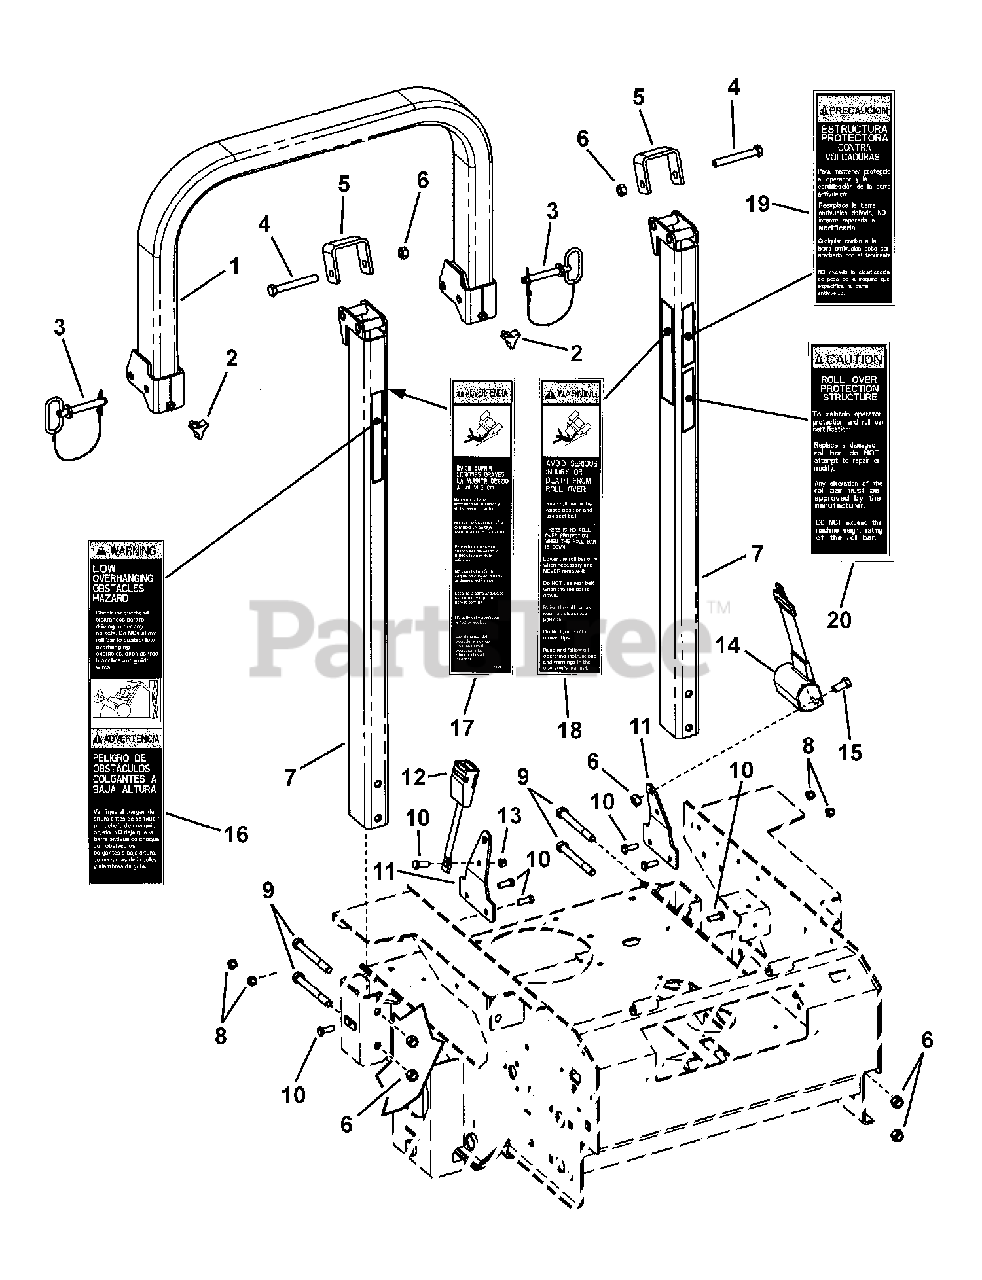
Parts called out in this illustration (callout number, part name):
1	WELDMENT, Loop
2	STAR KNOB (5/16-18 thread)
3	PIN, Hinge (ROPS)
4	BOLT, 1/2-13 x 3-3/4" Hex Head Cap
5	BRACKET, ROPS Stop, NZMX
6	NUT, 1/2-13 Hex Center Lock, GR 5
7	WELDMENT, Post
8	NUT, 3/8-16 HEX NYLON LOCK
9	BOLT, 1/2-13 x 4-1/2" Hex Head, GR 5
10	BOLT, 3/8-16 X 1" GD5 CZ
11	PLATE, Seat Belt
12	SEAT BELT, w/Metal Strap
13	NUT, 3/8-16 Hex Center Lock
14	RETRACTER, Seat Belt
15	SCREW, 1/2-13 x 1" Hex Head Cap, GR 5
16	DECAL, ROPS Overhang
17	DECAL, Warning ROPS (Spanish)
18	DECAL, Warning ROPS
19	DECAL, Caution ROPS (Spanish)
20	DECAL, Caution ROPS
